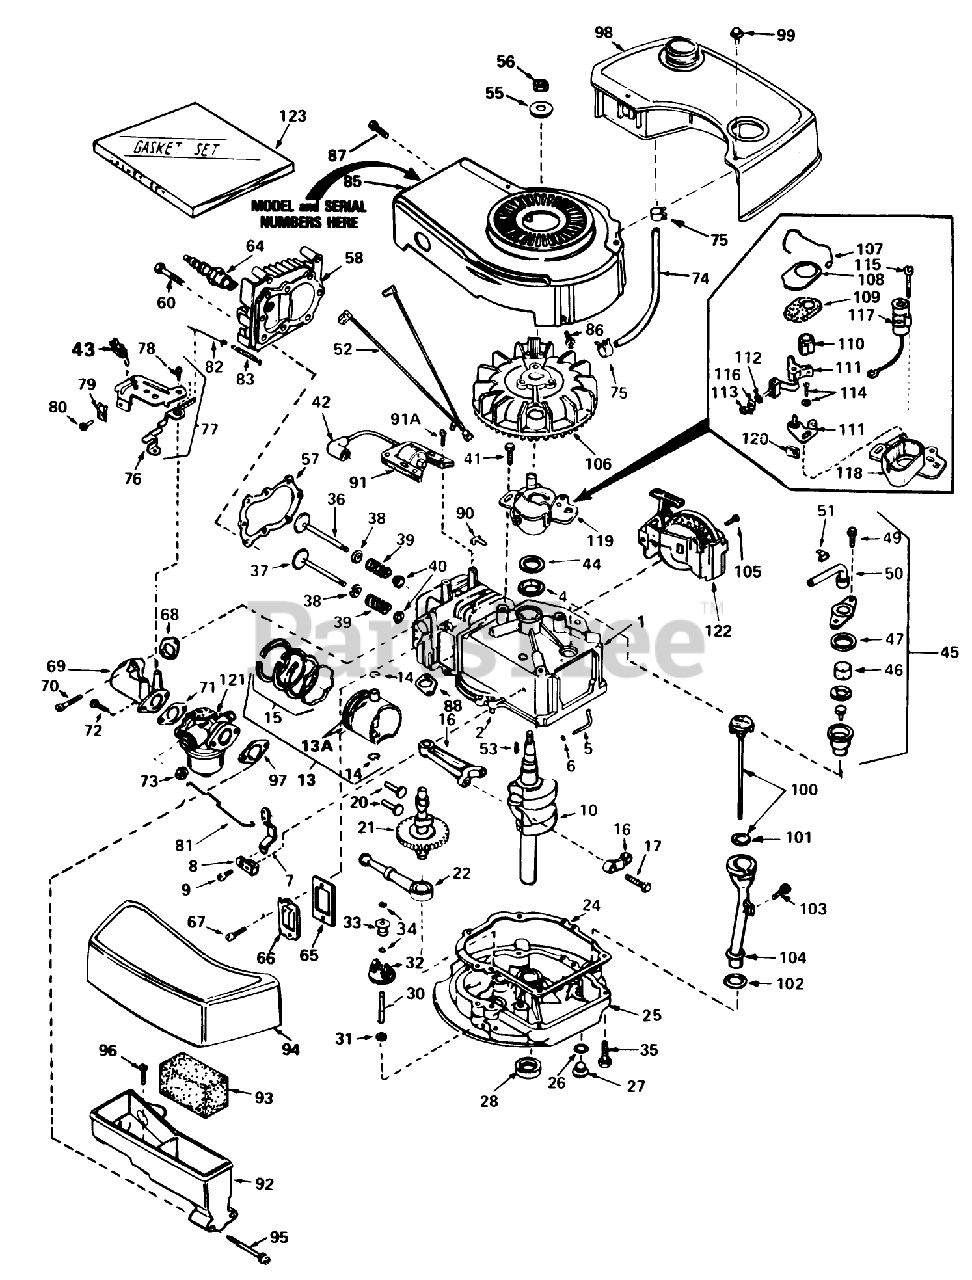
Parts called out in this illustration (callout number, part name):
1	Cyiinder Assy. (Incl. Ref. #2, 4 105)
2	Pin-Dowel
4	Seal-Oil
5	Rod, Governor (Incl. No. 36)
6	Washer-Flat
7	Governor Lever
8	Clamp-Lever, Governor
9	Screw
10	Crankshaft
13	Piston, Pin Ring Assy. (Std.) (Incl. Ref. #13A, 14 15)
13	Piston, Pin Ring Assy. (.010 oversize) (Incl. Ref. #13A, 14 15)
13	Piston, Pin Ring Assy. (.020 oversize) (Incl. Ref. #13A, 14 15)
13A	Piston Pin Assy. (Incl . Ref. . #14) (Std.)
13A	Piston Pin Assy. (Incl. Ref. #14) (.010 Oversize)
13A	Piston Pin Assy. (.020 oversize) (Incl. Ref. #14)
14	Ring-Retaining, Piston Pin
15	Ring Set (Std.)
15	Ring Set (.020" OS)
15	Ring Set (.010" OS)
16	Rod Assy., Connecting (Incl. Ref. #17)
17	Bolt-Rod, Connecting
20	Lifter-Valve
21	Camshaft(Mech.Comp. Release)
22	Oil Pump ASM
24	Gasket, Mounting
25	Flange Assy., Mounting (Incl. Ref. #26thru 30)
26	Gasket-Oil Drain
27	Plug Oil Drain
28	Seal Oil
30	Shaft-Governor
31	Washer-Flat
32	Governor Gear ASM
33	Spool-Governor
34	Ring-Retaining
35	Screw (1/4-20 x 1-1/4)
36	Valve, Intake (Std.) (Incl. Ref. #40)
36	Valve, Intake (1/32" oversize)(Incl. No. 40)
37	Valve, Exhaust (Std.)(Incl. No. 40)
37	Valve, Intake (1/32" oversize)(Incl. No. 40)
38	Cap-Upper Valve Spring
39	Spring-Valve
40	Cap-Valve, Spring
41	Screw
42	Cover-Spark Plug
43	Terminal
44	Gasket Stator
45	Breather Assy. (Incl. Ref. #46 thru 51)
46	Element-Breather
47	Gasket-Breather
49	Screw (10-24 x 9/16)
50	Tube, Breaker
51	Clip, Breather
52	Wire Ground
53	682488 LB GRASS HI-
55	Washer-Belleville
56	Nut-Flywheel
57	63573 GIL 42 SNWTHW
58	Head-Cylinder
60	Screw (5/16-18x1-1/2)
64	Plug, Spark (J17LM or equiv.)
64	Plug, Spark (Champion RCJ-8)
65	Gasket-Breather
66	Cover-Valve
67	Screw
68	Gasket-Intake
69	Pipe, Intake (Incl. No. 68)
70	Screw (1/4-20 x 1)
71	Gasket-Carburetor
73	Nut and Lock Washer (1/4-28)
74	Line-Fuel
75	Clamp-Line, Fuel
76	Lever Control
77	Control Assy., Speed (Incl. Nos, 76, 78 89)
78	Screw, Hex Washer Hd Shoulder Self-Tap
79	Conduit
80	Screw (10-32 x 3/8)
81	Link-Throttle
82	Link Governor Spring
83	Spring Governor
85	Housing Blower
86	Screw
87	Screw (10-24 x 9/16)
88	Gasket Exhaust
90	Clip-Wire
91	Lamination Coil Assy. (Incl. No. 42)
91A	Screw
92	Body Air Cleaner
93	Filer, Air
94	Cove, Air Cleaner
95	Screw Fil Hd.
96	Screw, Hex Hd.
97	Gasket-Air Cleaner
98	Tank, Fuel
99	Screw (10-32 x 35/64)
100	Dipstick, Oil (Incl. Ref. #101)(Twist Lock)
101	O-Ring
102	Gasket
103	Screw (10-32 x 1/2)
104	Tube-Oil Fill
105	Screw (1/2-20x5/8)
106	FIywheel
107	Spring Breaker Box
108	Cover-Dust
109	Gasket-Dust Cover
110	Cam-Breaker
111	Breaker Assy.
112	Washer
113	DECAL
114	Breaker Screw
115	Condenser Screw
116	Terminal, Ground
117	Condenser
118	Stator Plate
119	Stator Plate Assy. (incl. Nos. 107, 111 thru 118 120)
120	Felt,Cam Wiper
121	Carburetor (Incl. Ref. #71)
122	Starter-Sidemount
123	Gasket Set
